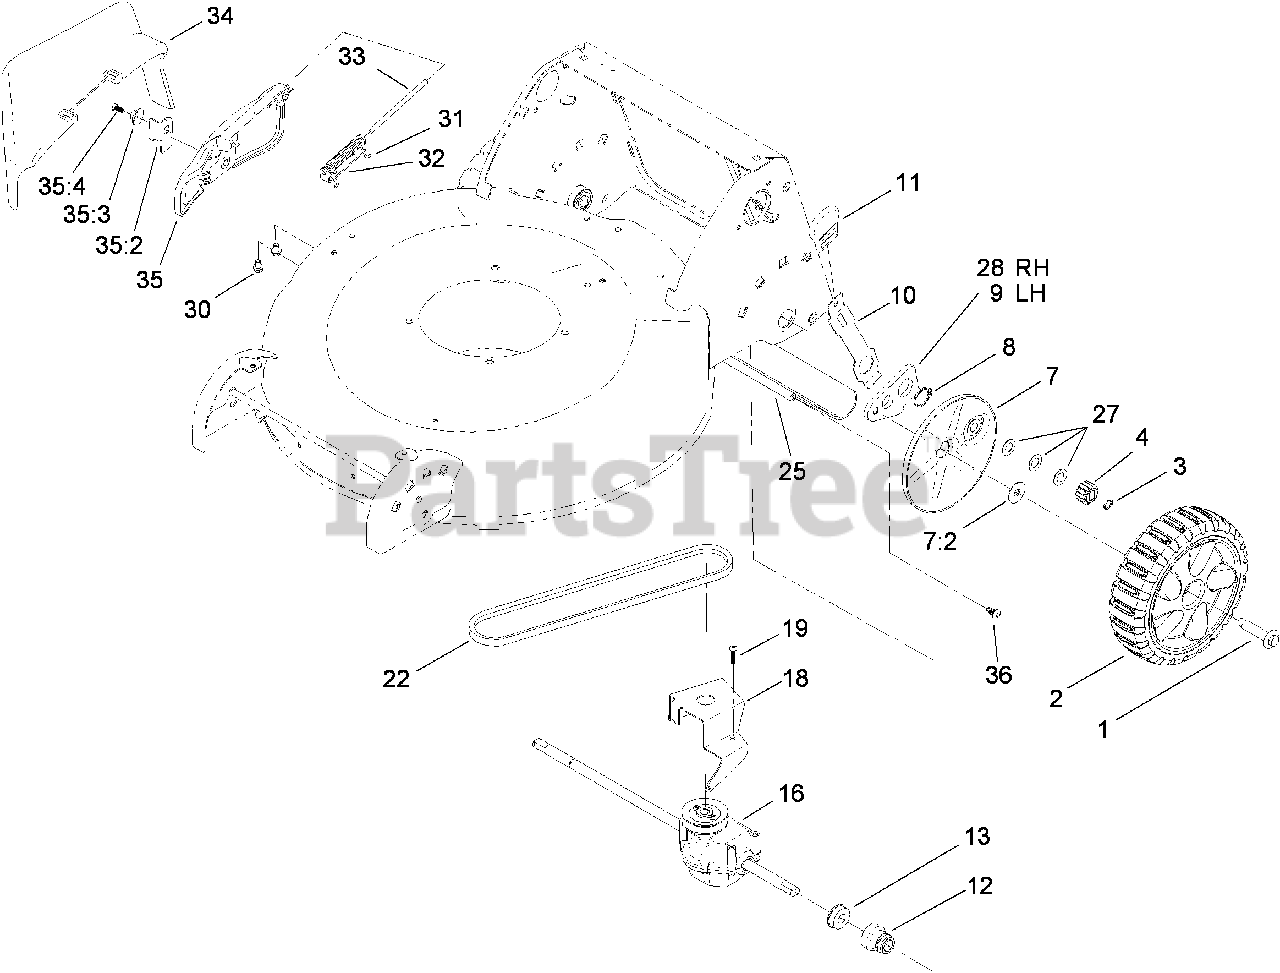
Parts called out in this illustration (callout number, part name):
1	BOLT-SHOULDER
2	REAR WHEEL ASM
3	RING-RETAINING
4	PINION
7	WHEEL COVER ASM
7:2	WASHER-STEPPED
8	RING-RETAINING
9	ARM-REAR PIVOT, LH
10	ARM-SPRING, REAR
12	RETAINER-BEARING, HOC
13	BEARING-BALL
16	TRANSMISSION ASM
18	BRACKET-TRANSMISSION
19	SCREW-PLASTITE
25	SHIELD-TRAILING
27	WASHER-PLAIN
30	SCREW-HWH
31	SPRING-TORSION
32	BRACKET-COVER
33	ROD-COVER
34	CHUTE-DISCHARGE, SIDE
35	DISCHARGE DOOR ASM
35:2	LATCH-DOOR
35:3	CAP-DOOR
35:4	SCREW-PLASTITE
36	SCREW-PTH
